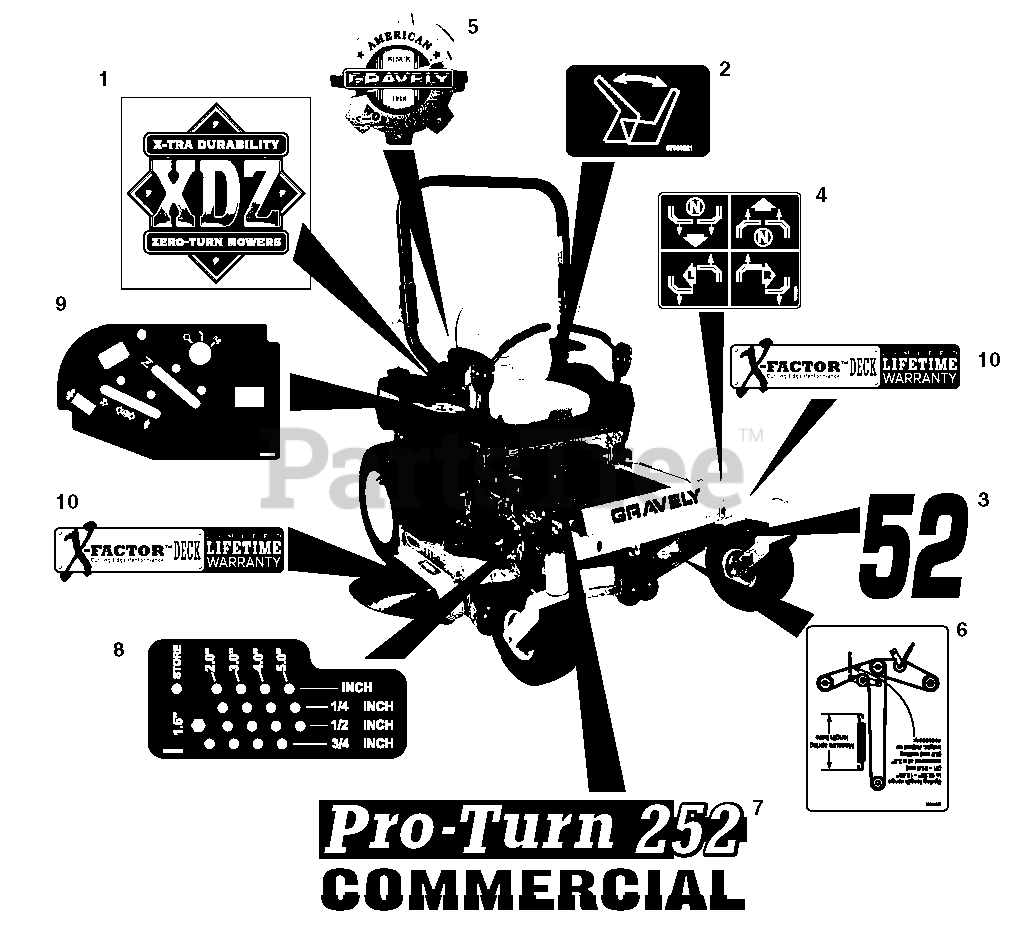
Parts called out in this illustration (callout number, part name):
1	Decal, XDZ
2	Decal, Seat Release
3	Decal, 52
4	Decal, Instructional- Steering
5	Decal, Gravely Heritage, Large
6	Decal, Belt Routing
7	Decal, Pro-Turn 252
8	Decal, Height of Cut
9	Decal, Control Panel
